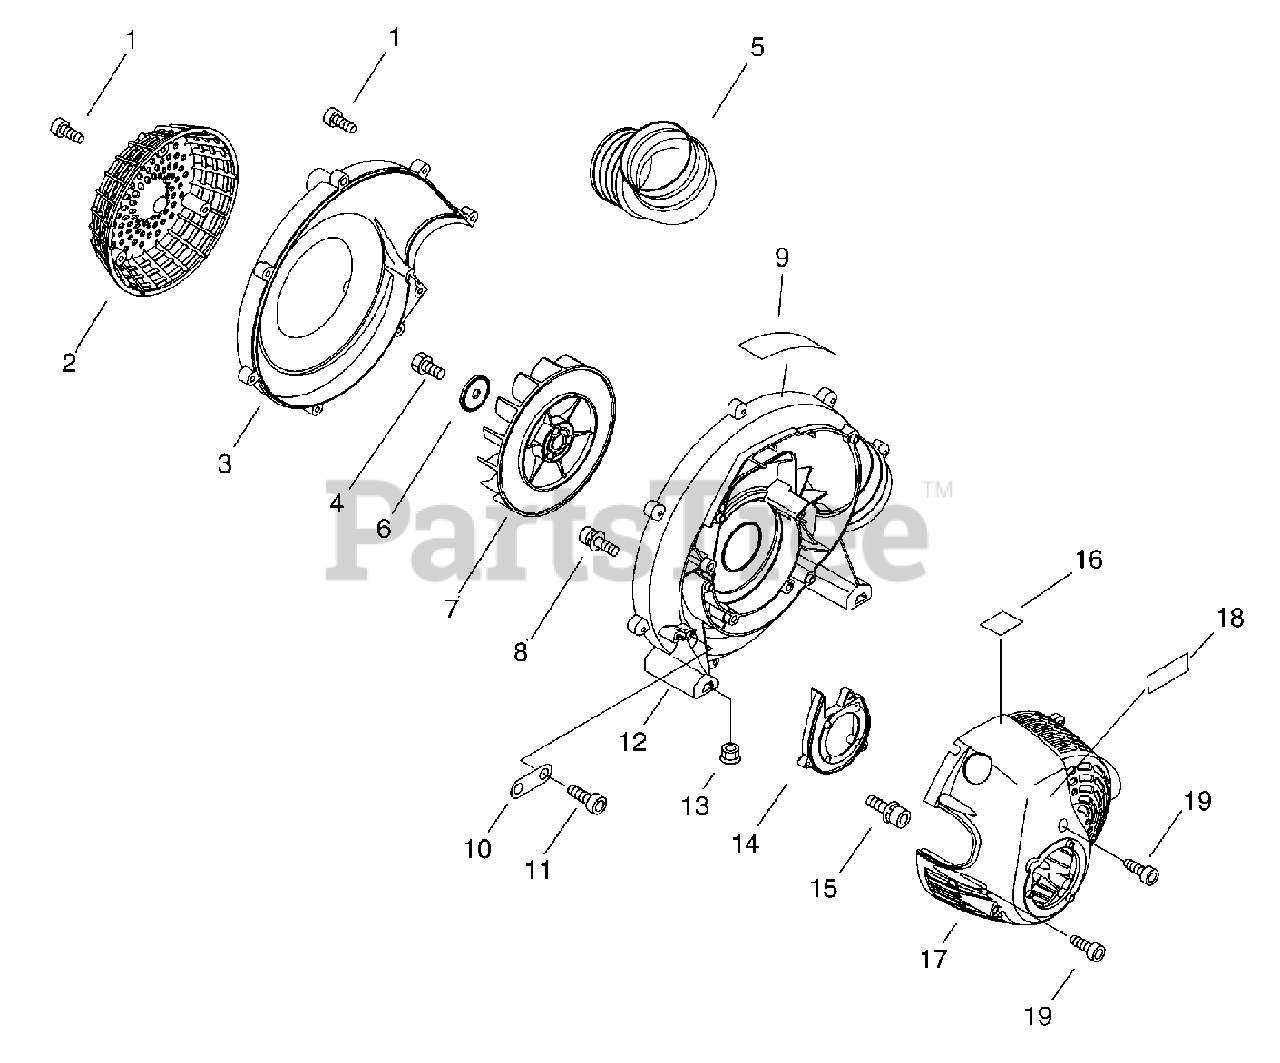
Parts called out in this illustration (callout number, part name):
1	SCREW - 5X20 -- TAPPING
2	GUARD, DEBRIS
3	COVER, FAN - LEFT
4	BOLT- 8X14
5	TUBE, BLOWER - ELBOW
6	WASHER - CUP
7	FAN
8	SCREW - 4X20
9	LABEL - CAUTION
11	SCREW - 5X16
12	COVER, FAN - RIGHT
13	NUT - 5
15	SCREW - 4X16
16	LABEL - HOT SURFACE
17	COVER, ENGINE
18	LABEL - MODEL PB-265LN
19	SCREW - 5X16
